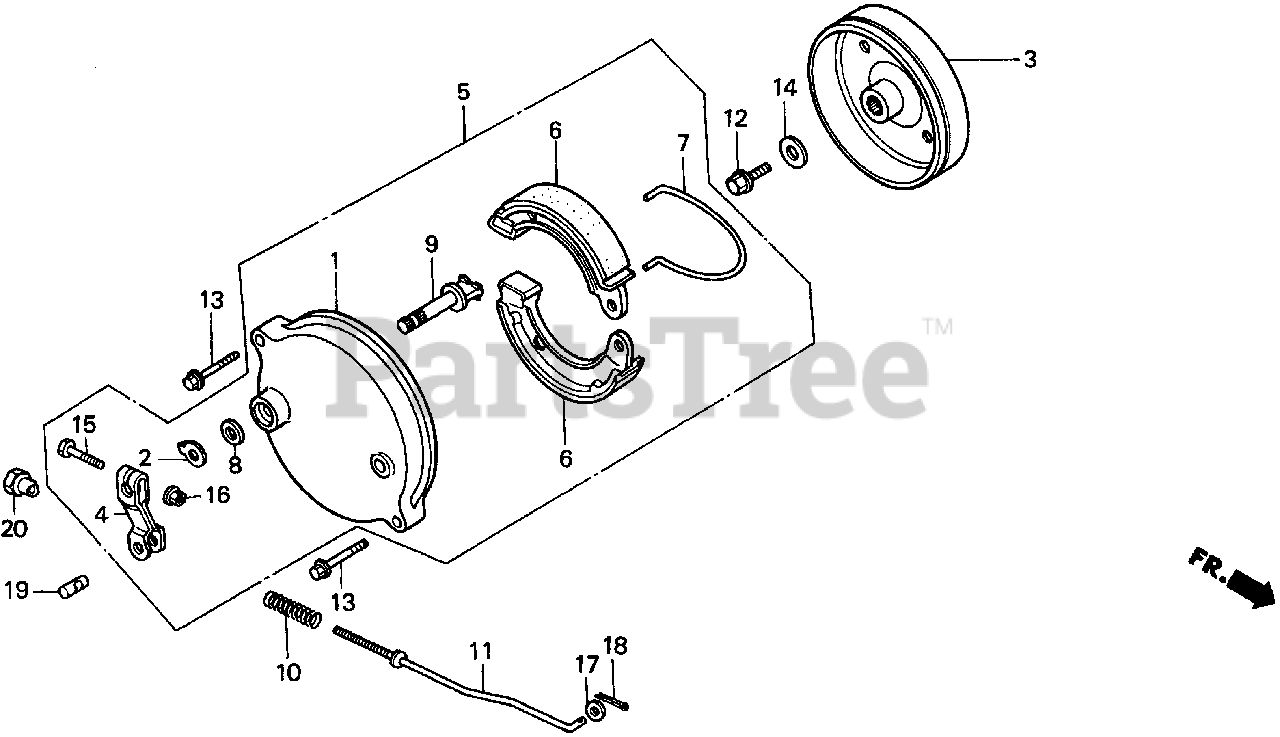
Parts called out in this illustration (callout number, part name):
1	PANEL, BRAKE
2	INDICATOR, BRAKE
3	DRUM, BRAKE
4	ARM, RR. BRAKE
5	PANEL ASSY., BRAKE
6	SHOE, BRAKE
6	SHOE, BRAKE (ASK)
6	SHOE, FR. BRAKE (NIPPON) (NOT AVAILABLE)
7	SPRING, BRAKE SHOE
8	SEAL, BRAKE CAM
9	CAM, FR. BRAKE
10	SPRING A, BRAKE ROD
11	ROD C, FOOT BRAKE
12	BOLT, FLANGE (8X20)
13	BOLT, FLANGE (6X28)
14	WASHER, SPECIAL (28X8.5X4.0)
15	BOLT, HEX. (5X25) (SOURCE: VINTAGE PARTS INC.)
16	NUT, FLANGE (5MM)
17	WASHER, PLAIN (5MM)
18	PIN, COTTER (2.0X15)
19	JOINT A, BRAKE ARM
20	NUT A, BRAKE ROD ADJUSTING
